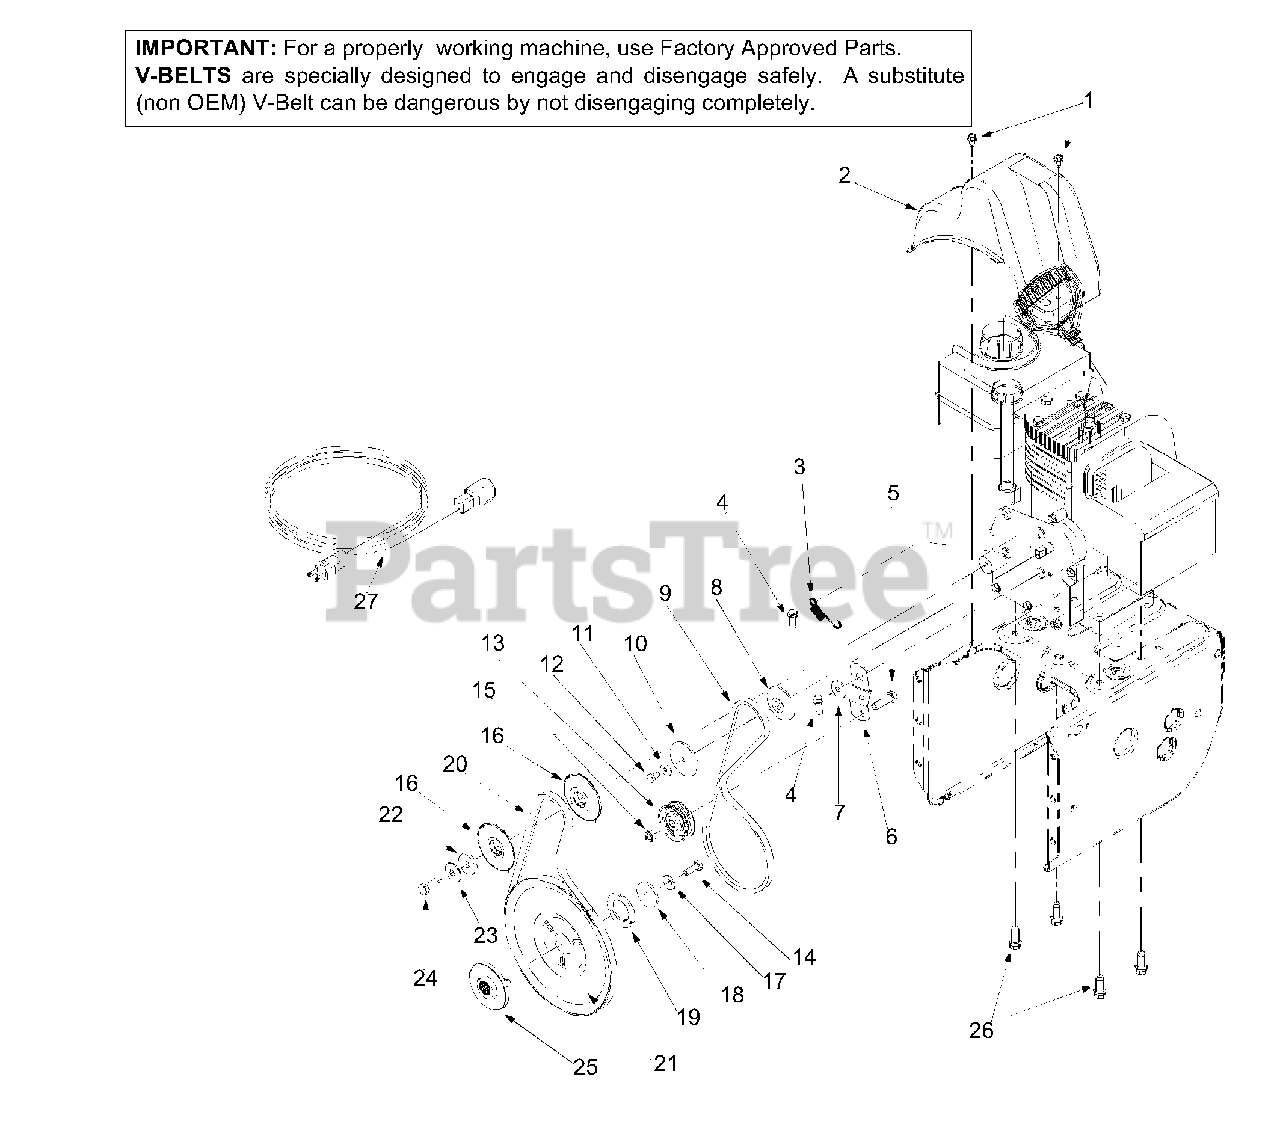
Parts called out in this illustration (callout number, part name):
1	Hex Washer Screw 1/4-20 x.5
2	Belt Cover
3	Extension Spring
4	Hex Screw 5/16-24 x .75
5	Hex Cap Screw 3/8-16 x 1.25
8	Pulley Half
9	V-Belt
10	Pulley Half
11	Bell Washer
12	Hex Cap Screw 1/4-28 x .50
13	Flat Idler
14	Lock Cap Screw 5/16-24
15	Lock Jam Nut 3/8-16
16	Pulley Half
17	Bell Washer
18	Flat Washer
19	Washer
20	Belt
21	Auger Pulley
22	Flat Washer
23	Bell Washer
24	Hex Cap Screw 3/8-24
25	Pulley
26	Hex Washer Screw 3/8-16 x 1.0
27	Extension Cord
